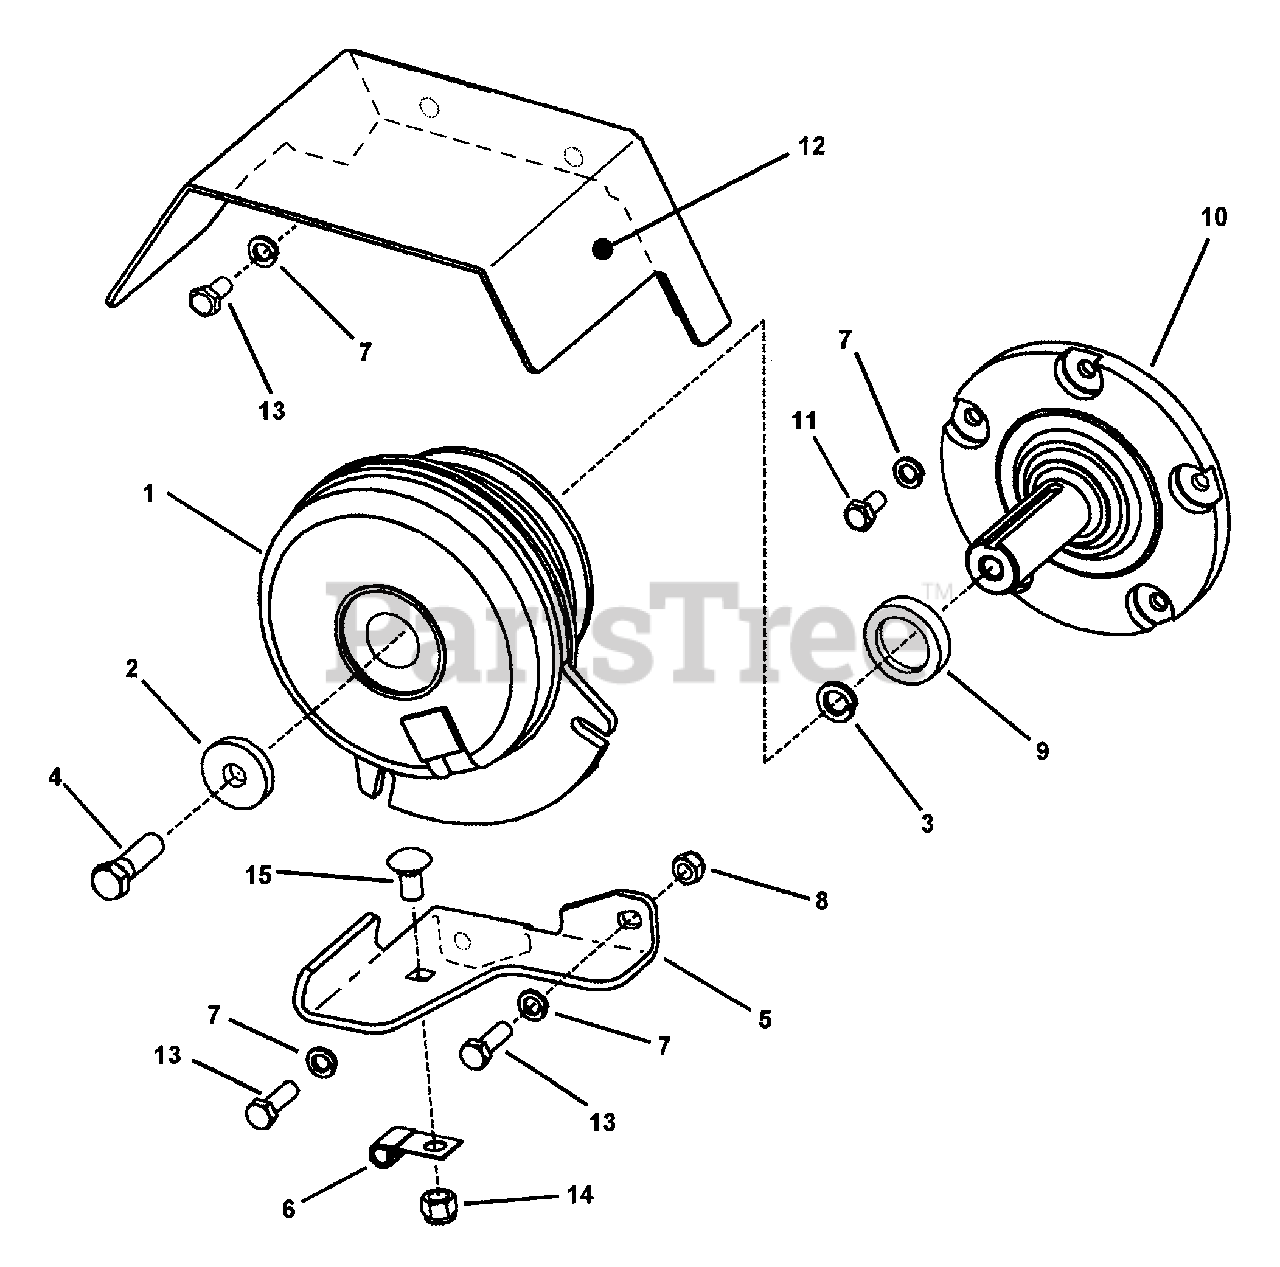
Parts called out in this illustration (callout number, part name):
1	ELECTRIC CLUTCH
2	SPACER, Clutch
3	WASHER, 7/16 Split Lock
4	SCREW, 7/16-20 x 1-1/2" Hex Head Cap, Grade 5
5	BRACKET, Clutch Torque
6	J-CLIP, 3/8" Open Cushioned
7	WASHER, .32 Split Lock
8	NUT, M8-1.25 Hex Nyloc
9	SPACER, Clutch
10	SHAFT, PTO
11	SCREW, M8-1.25 x 16mm Hex Head Cap
12	BRACKET, Clutch Guard
13	BOLT, M8-1.25 X 25MM GD8.8
14	NUT, 3/8-16 HEX NYLON LOCK
15	BOLT, 3/8-16 x 3/4" Square neck Carriage
